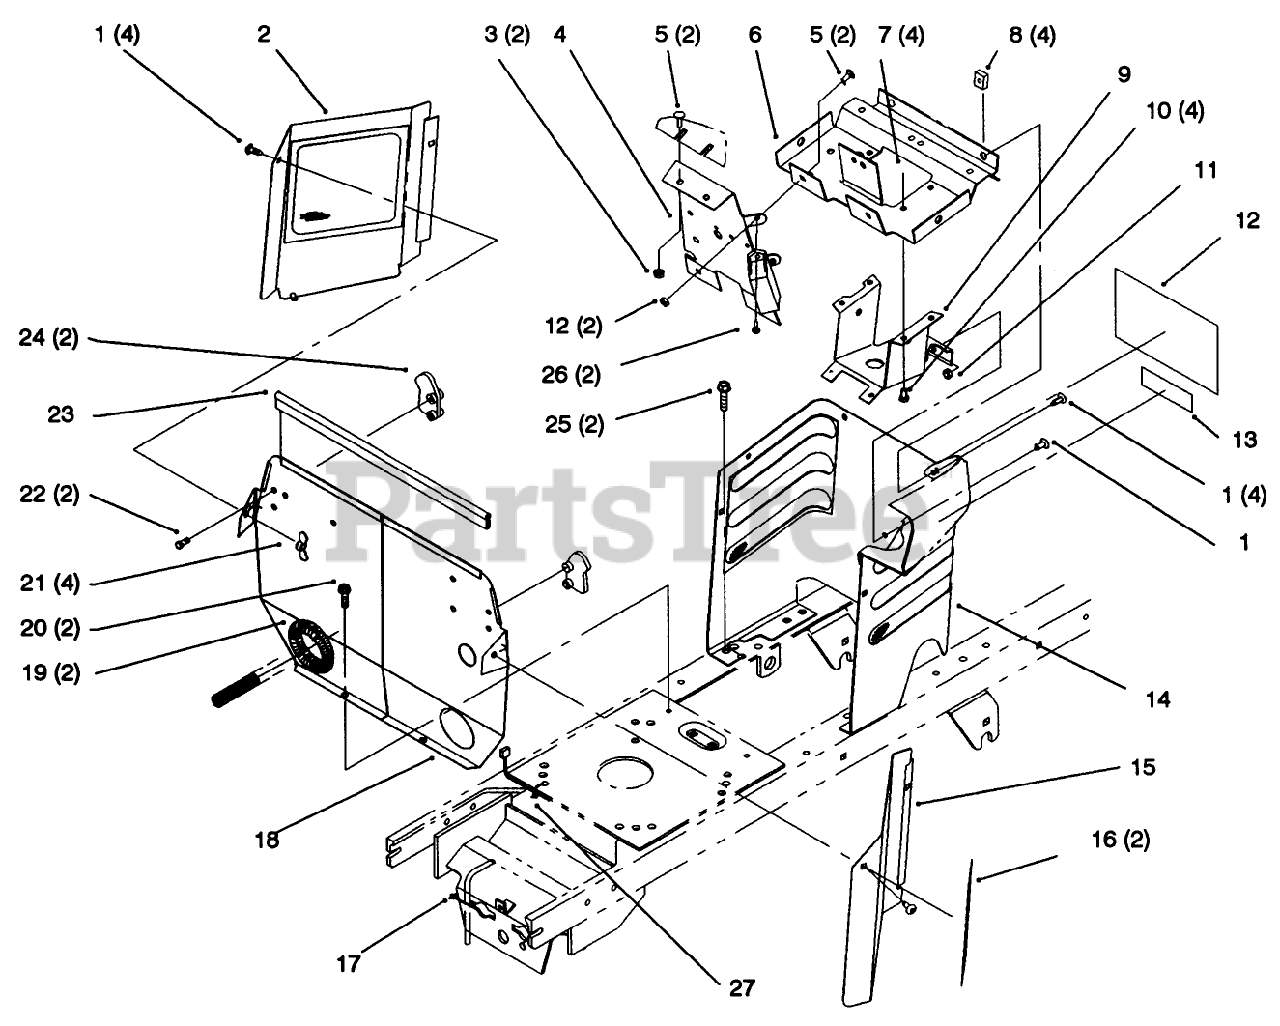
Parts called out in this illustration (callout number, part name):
1	SCREW-HH
2	Cover-Side RH
3	NUT-KEPS
4	Panel-Support
5	SCREW-CARR
6	Support-Dash
7	NUT-HEX
8	NUT RETAINER - J TYPE
9	Support-Column
10	SCREW-HH
11	NUT-LOCK, NI
12	DECAL-DANGER
13	DECAL-INSTRUCTION
14	Hoodstand W/Decals
15	Cover-Side LH
17	TIE-CABLE
18	Firewall
19	COVER-SHAFT, DRIVE
20	SCREW-HWH
21	NUT-WING
22	SCREW-PLASTITE
23	TRIM-SEAL, FIREWALL
24	LATCH-HOOD
25	SCREW-HWHTF
26	SCREW-PPHTF
27	TIE-CABLE
